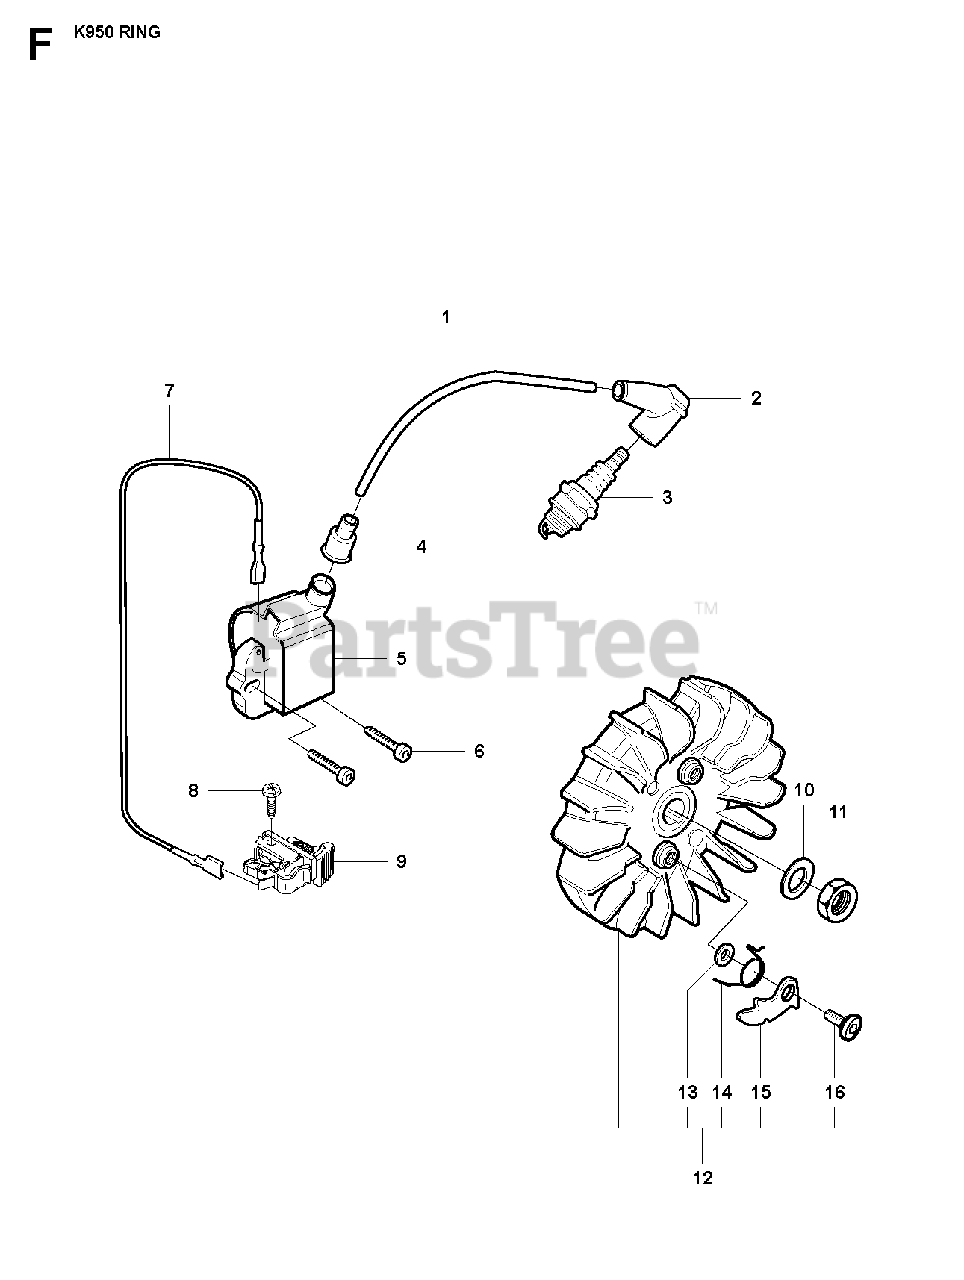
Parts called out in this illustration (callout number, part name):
1	IGNITION CABLE
2	SPARK PLUG CAP
3	SPARK PLUGRCJ 7Y
5	IGNITION SYSTEM
8	SCREW CCRPANT
9	STOP SWITCH
12	FLYWHEELIncl. 13, 14, 15, 16
